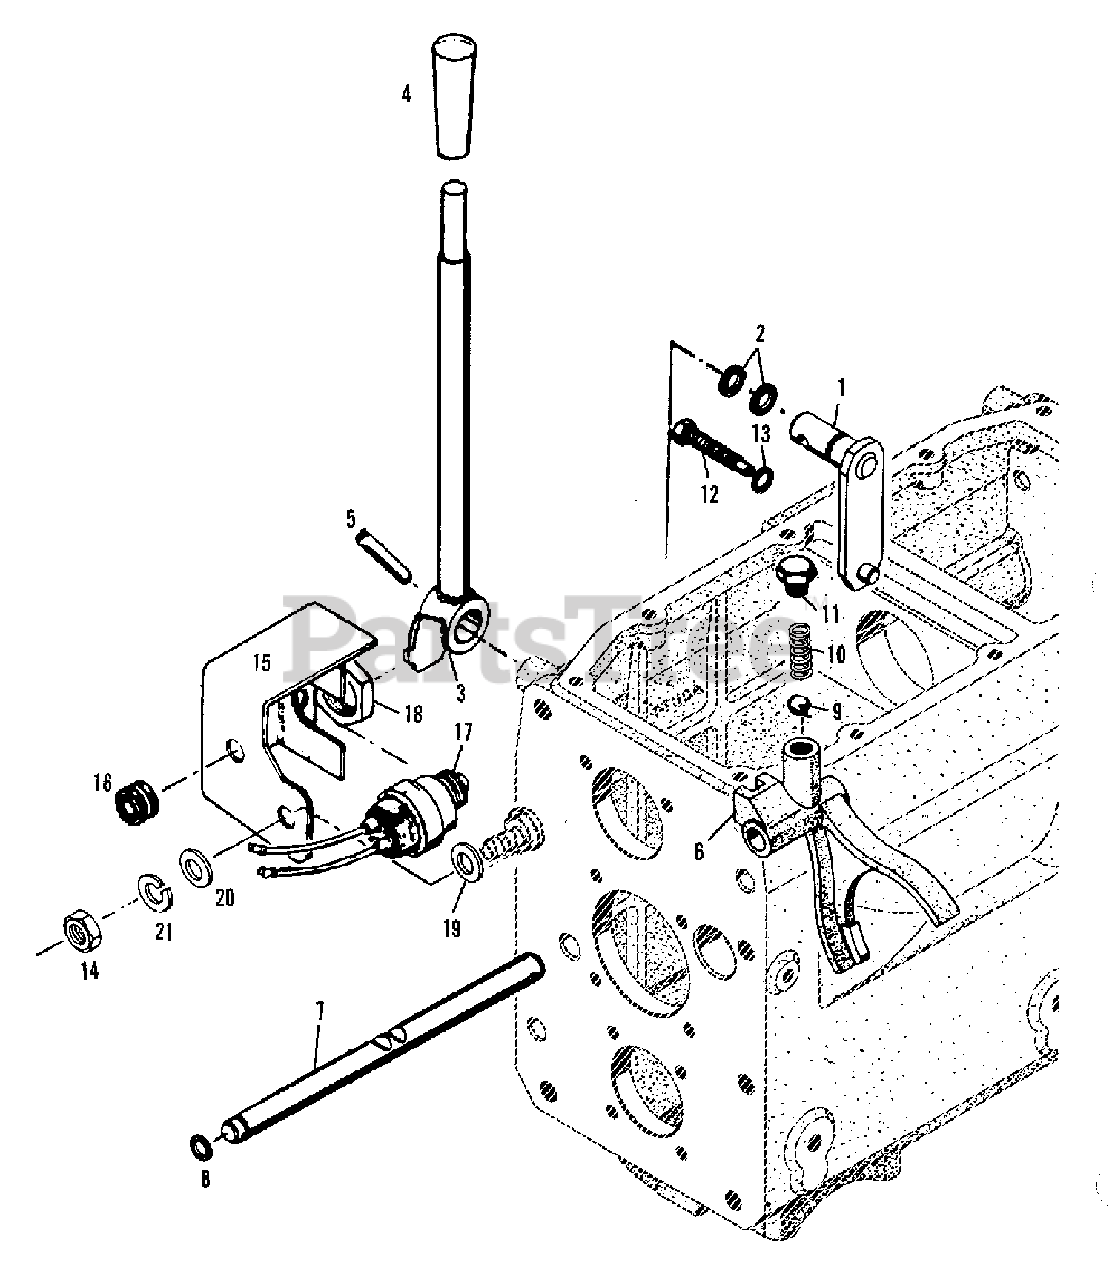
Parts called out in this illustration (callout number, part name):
1	LEVER, shift-P.T.O.
3	LEVER ASSEMBLY, P.T.O. control (Incl. Item 4)
4	KNOB, control lever (red)
5	PIN, M8 x 28 lock
6	FORK, P.T.O.
7	ROD, shifter, P.T.O.
9	BALL, detent
10	SPRING, detent
11	SCREW, detent
12	SCREW, lock-P.T.O. shifter rod
13	WASHER, seal
15	COVER, switch
17	SWITCH ASSEMBLY, safety start - P.T.O.
19	WASHER (0.5)
19	WASHER, (1)
20	WASHER, M12
21	LOCKWASHER, M12
